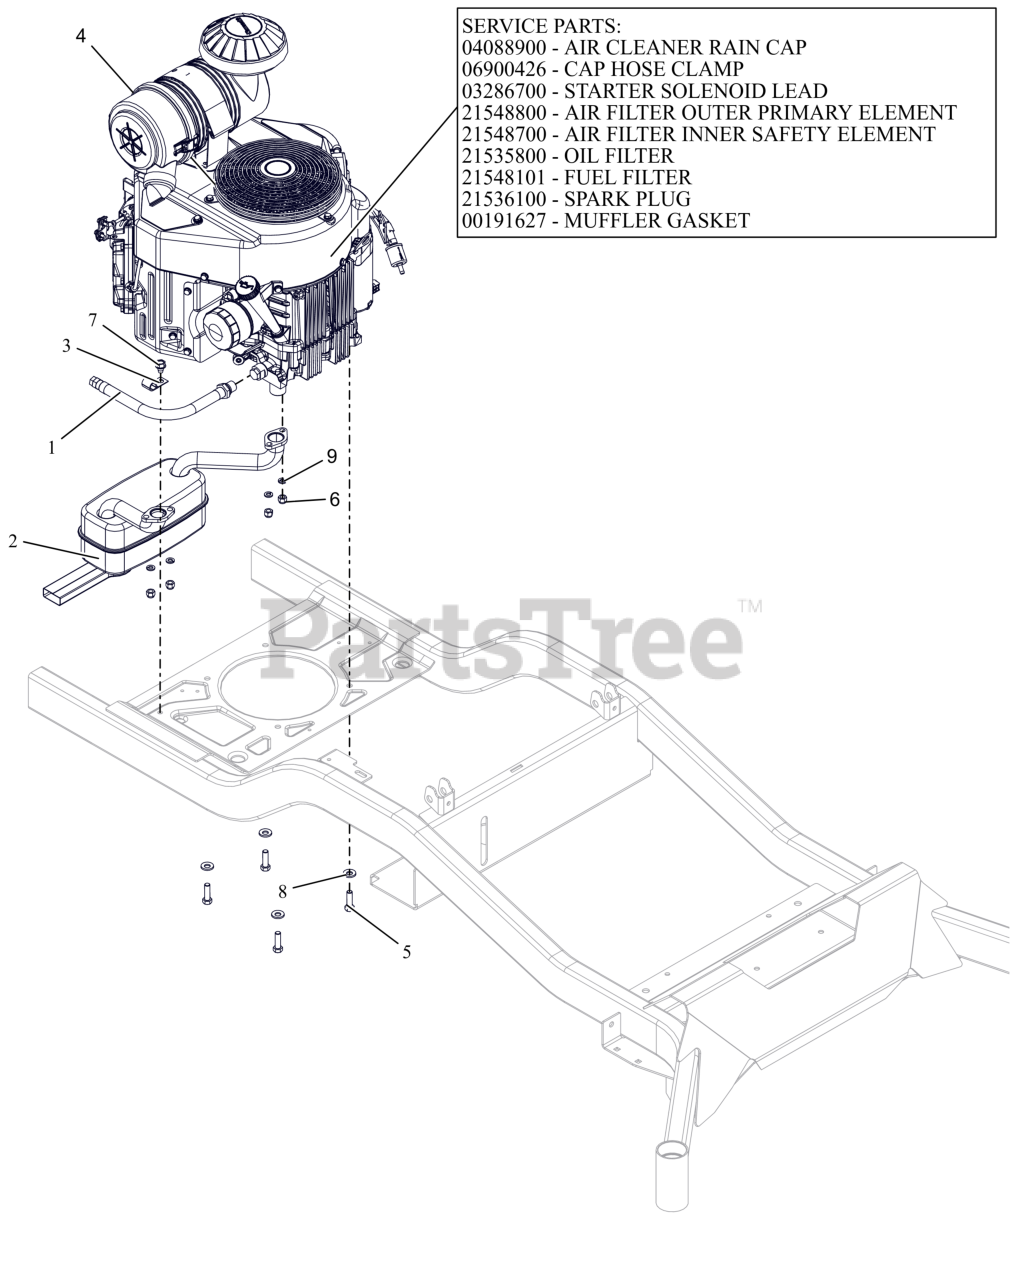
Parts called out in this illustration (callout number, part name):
1	HOSE, OIL DRAIN
2	MUFFLER, KAWASAKI
3	J-CLAMP
4	ENGINE, KAWASAKI - FX730
4	CAP, KAW 11065-7025
4	CLAMP, HOSE #36 SS 1.813-2.75
4	LEAD - STARTER SOLENOID
4	FILTER, OUTER
4	FILTER, INNER - KAW
4	FILTER,OIL - KAW
4	FUEL FILTER-KAWASAKI FR
4	PLUG, SPARK
4	GASKET, MUFFLER S/O
5	BLT, HEX .38-16X1.25 G5 ZCC NT
6	NUT, LK-CTR-JAM M8-1.25 GR8.8 ZC120
7	SCR,TAP .375-16X.50 HWH TR ZCC
8	WASHER, 3/8" SPRING DISC
9	WSHR,LK-REG .312X.078 ZCC
